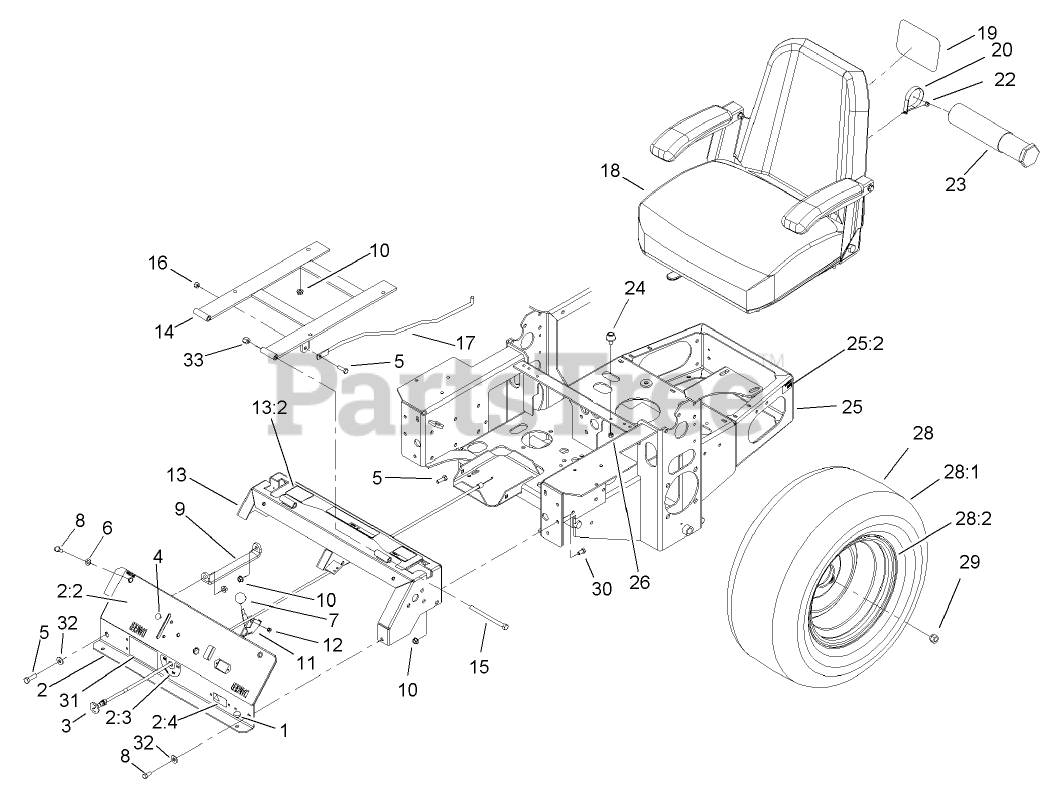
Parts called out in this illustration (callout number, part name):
1	BUMPER
2	CONSOLE ASM
2:2	DECAL-PANEL, CONTROL
2:3	DECAL-VALVE, FUEL
2:4	DECAL-PROTECTION, EAR
3	Control-Choke
4	BOLT-CARR
5	SCREW-HH
6	WASHER-PLAIN
7	KNOB-BALL
8	SCREW-HH
9	BRACKET
10	NUT-HF
11	Control-Throttle
12	NUT-LOCK, NI
13	CONSOLE FRAME ASM
13:2	DECAL-CONSOLE, TOP
14	FRAME-SEAT
15	SCREW-HH
16	NUT-LOCK, NI
17	ROD-RETAINER, SEAT
18	SEAT ASM
19	DECAL
20	CLAMP-R
22	SCREW-HWHTF
23	TUBE-MANUAL
24	BUMPER
25	Main Frame ASM
25:2	DECAL-SURFACE, HOT
26	NUT-LOCK, NI
28	WHEEL AND TIRE ASM
28:1	TIRE
29	NUT-LUG
30	SCREW-HH
31	DECAL
32	WASHER-FLAT
33	NUT-LOCK, NI
